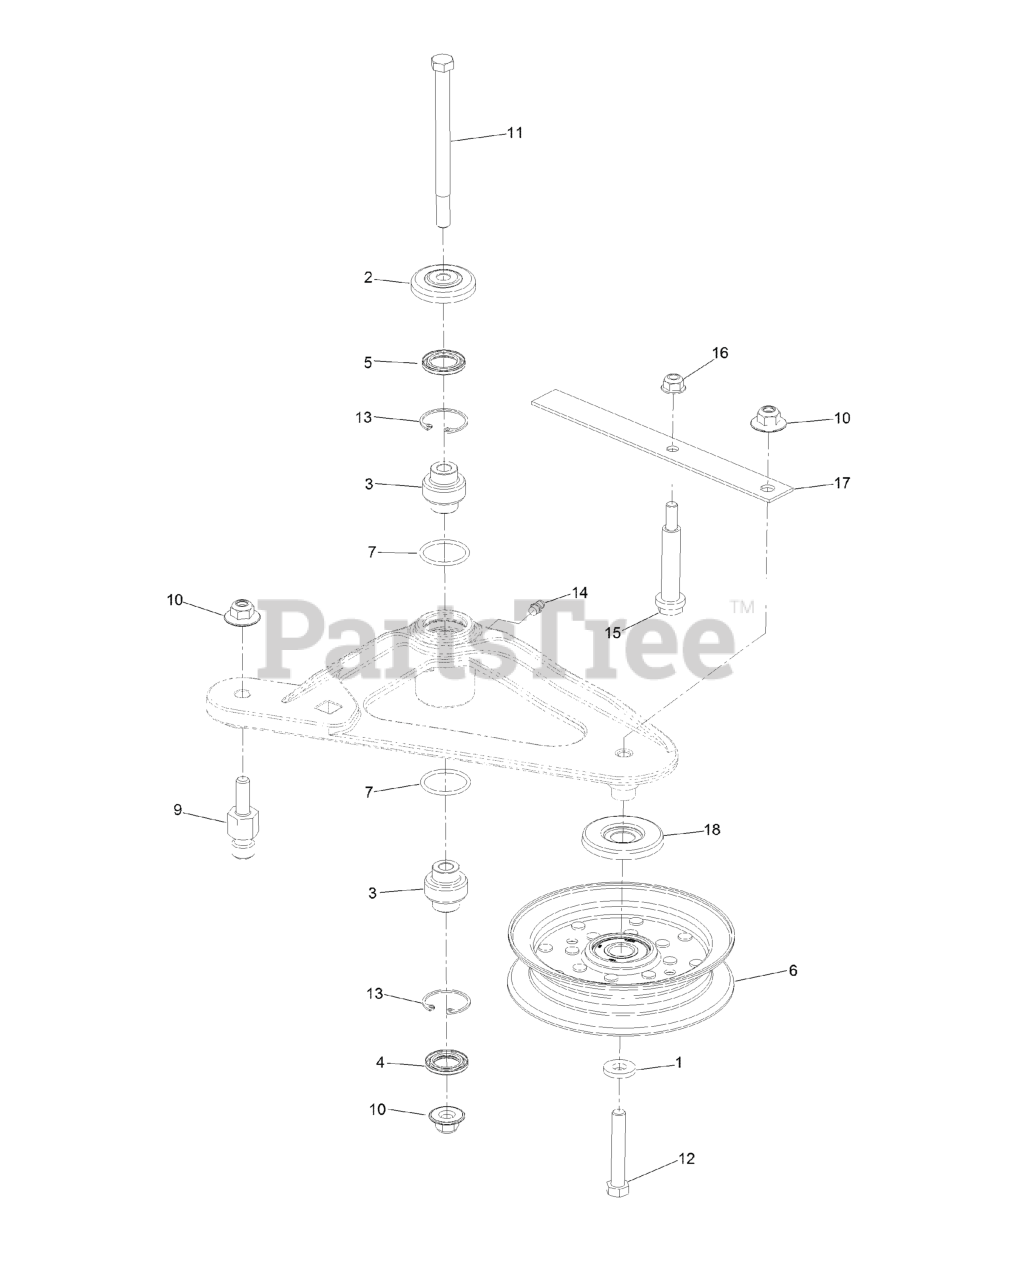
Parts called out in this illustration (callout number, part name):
2	GUARD-TOP
3	BEARING-SPHERICAL
4	SEAL-LIP, DOUBLE
5	SEAL-LIP, SINGLE
6	IDLER-PULLEY, FLAT
9	PIN-SPRING, ANCHOR
10	Nut-Nyloc 3/8-16 Flg
11	SCREW-SHOULDER, HH
12	SCREW-HH
13	RING-SNAP
14	FITTING-GREASE
15	BOLT-SHOULDER
16	NUT-HF, NI
17	SPRING-BELT
18	SHIELD-GUARD, DUST
